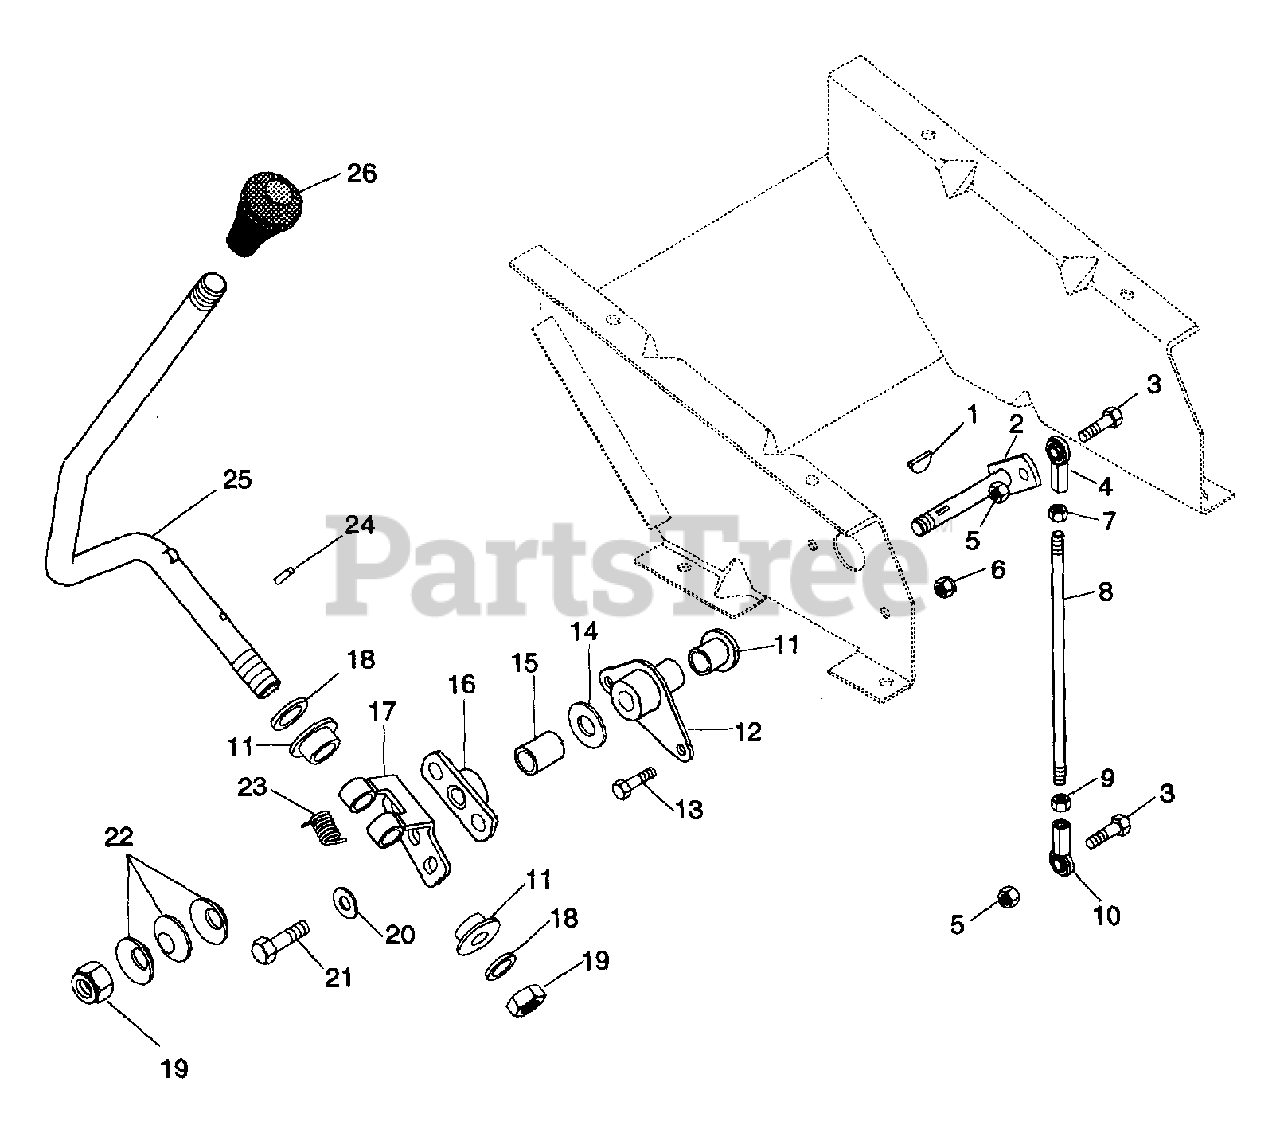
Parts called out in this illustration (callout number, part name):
1	KEY-WDRF .125X.500X.203 SAE 3
3	BLT-HEX .25-20X1.00 PL GR5
4	ROD END, 1/4 RH
5	NUT-LK-NYL .250-20 PL
6	NUT-LK-NYL.312-18 PL
7	NUT-HEX .250-28
8	SHIFT ROD
9	NUT-LH .250-28 GR2 PL
10	WSHR,SPCR - 1.08X1.50X.131
11	BSHG-FLG .500X.625X.625X.875
13	BLT-HEX .31-18X.75 PL GR5
14	FRICTION WASHER
15	BSHG-SLV .500X.625X.500
17	OUTER ARM
18	WSHR-FL-STL.531X1.00X.063 YWZC
19	NUT-LK .50-20 PL
20	WSHR-FL-STL.406X.812X.065PL
21	BLT-HEX .38-16X1.00 PL GR5
22	SPRING WASHER
23	SG_TORS .08X.56X.65
24	PIN-ROLL .125X1.00
25	SHIFT LEVER
